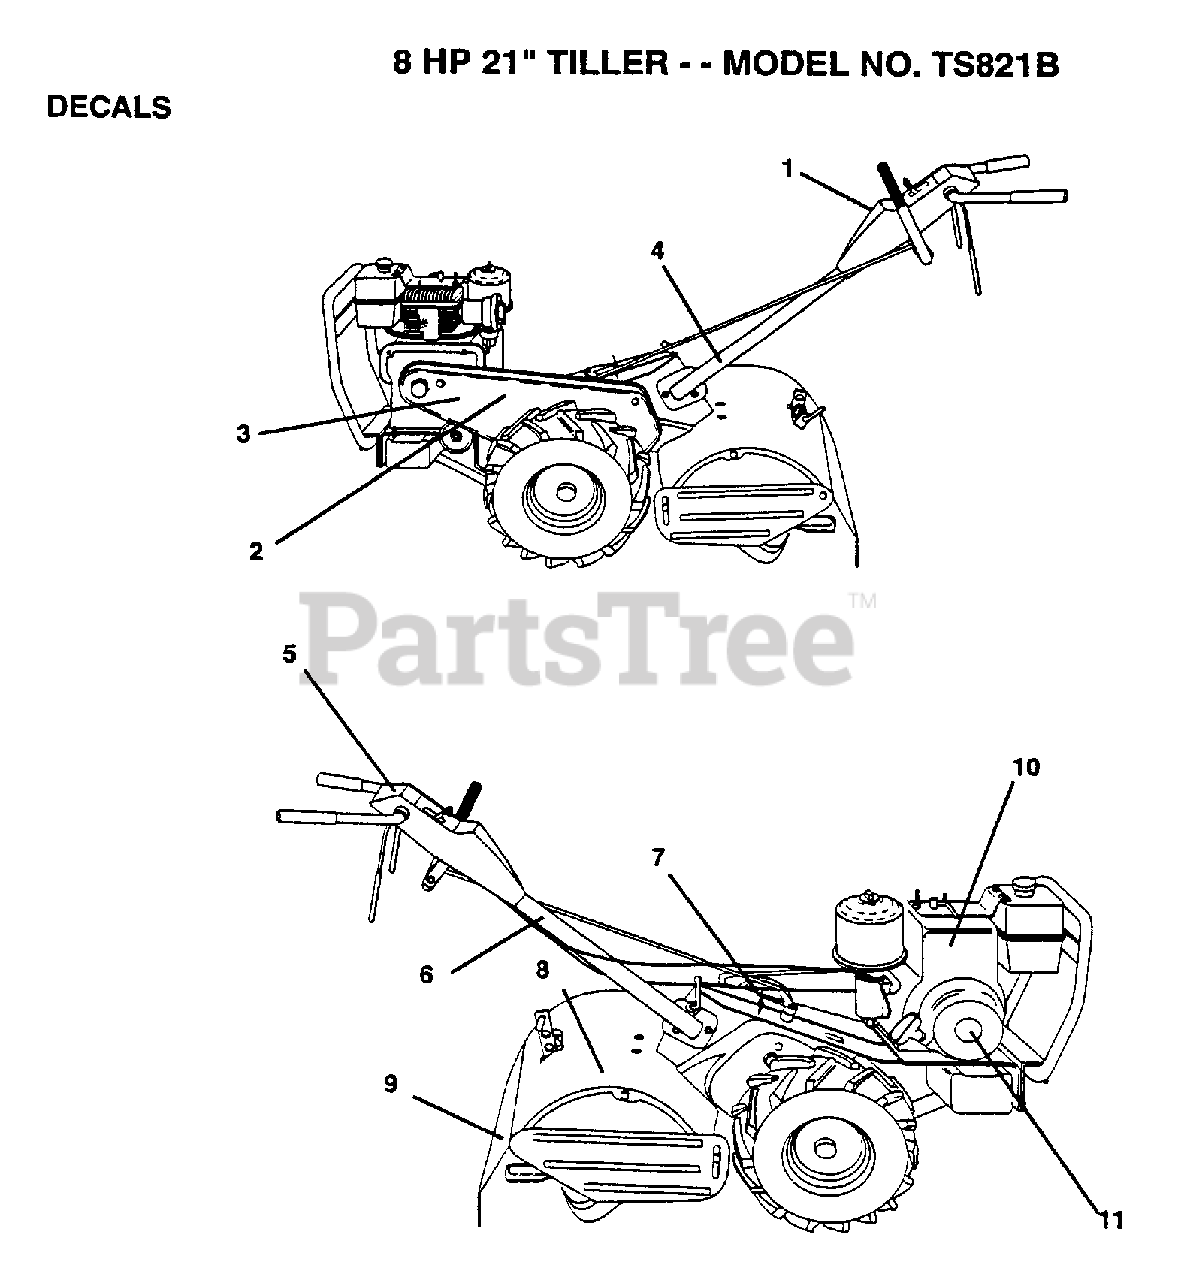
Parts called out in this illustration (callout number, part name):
1	DECAL.PNL.CTRL.
2	NAMEPLATE.HUSKEE
3	DECAL.GUARD.BELT
4	DECAL.BAR.USA.HUS
5	DECAL.INST.PNL.CT
6	DECAL TI
7	DECAL.SHIFT.IND.
9	DECAL TI
10	DECAL.ENG.B&S.8HP
11	DECAL.ENG.B&S.8HP
